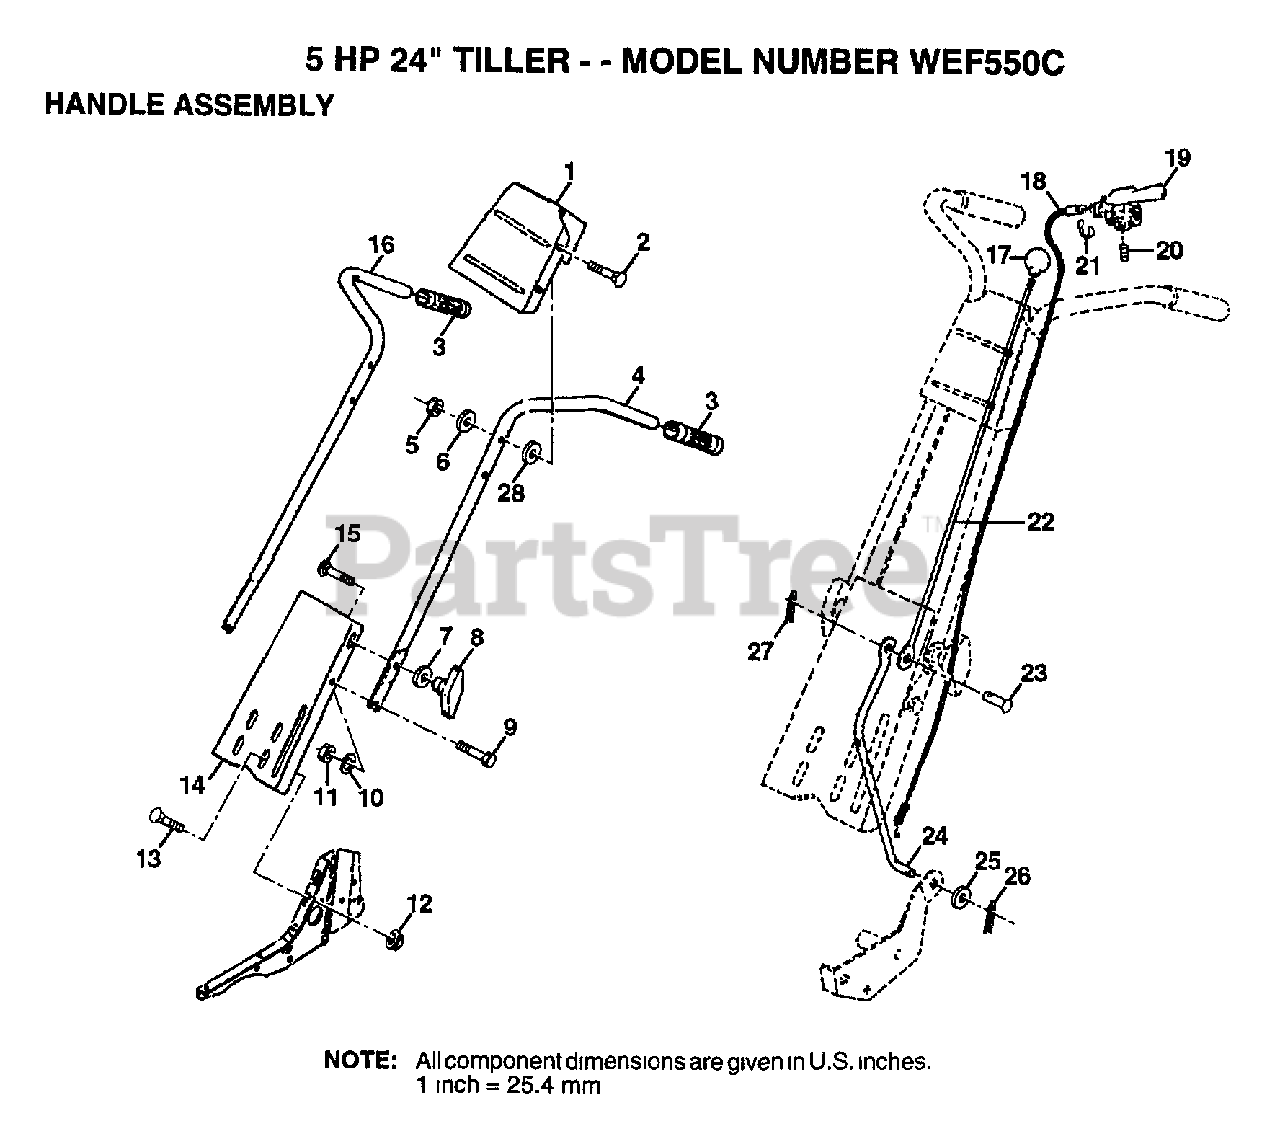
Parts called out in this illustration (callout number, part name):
1	HANDLE BRACKET
2	BOLT
3	GRIP NUB DOUBLE
4	HANDLE PNT LH
6	WASHER
7	WASHER
8	KNOB HANDLE
10	LOCKWASHER
11	NUT.HEX.5/16-18
12	NUT
13	BOLT
15	BOLT
16	HANDLE PNT RH
17	KNOB T(3/8 HOLE)
18	CABLE CLUTCH T
19	CONTROL LEVER TI
20	SCREW
21	E-RING
22	ROD REVERSE TI
23	RIVET.RD.HD.DRILL
24	REVERSE ROD TI
25	WASHER
26	COTTER PIN
28	WASHER
